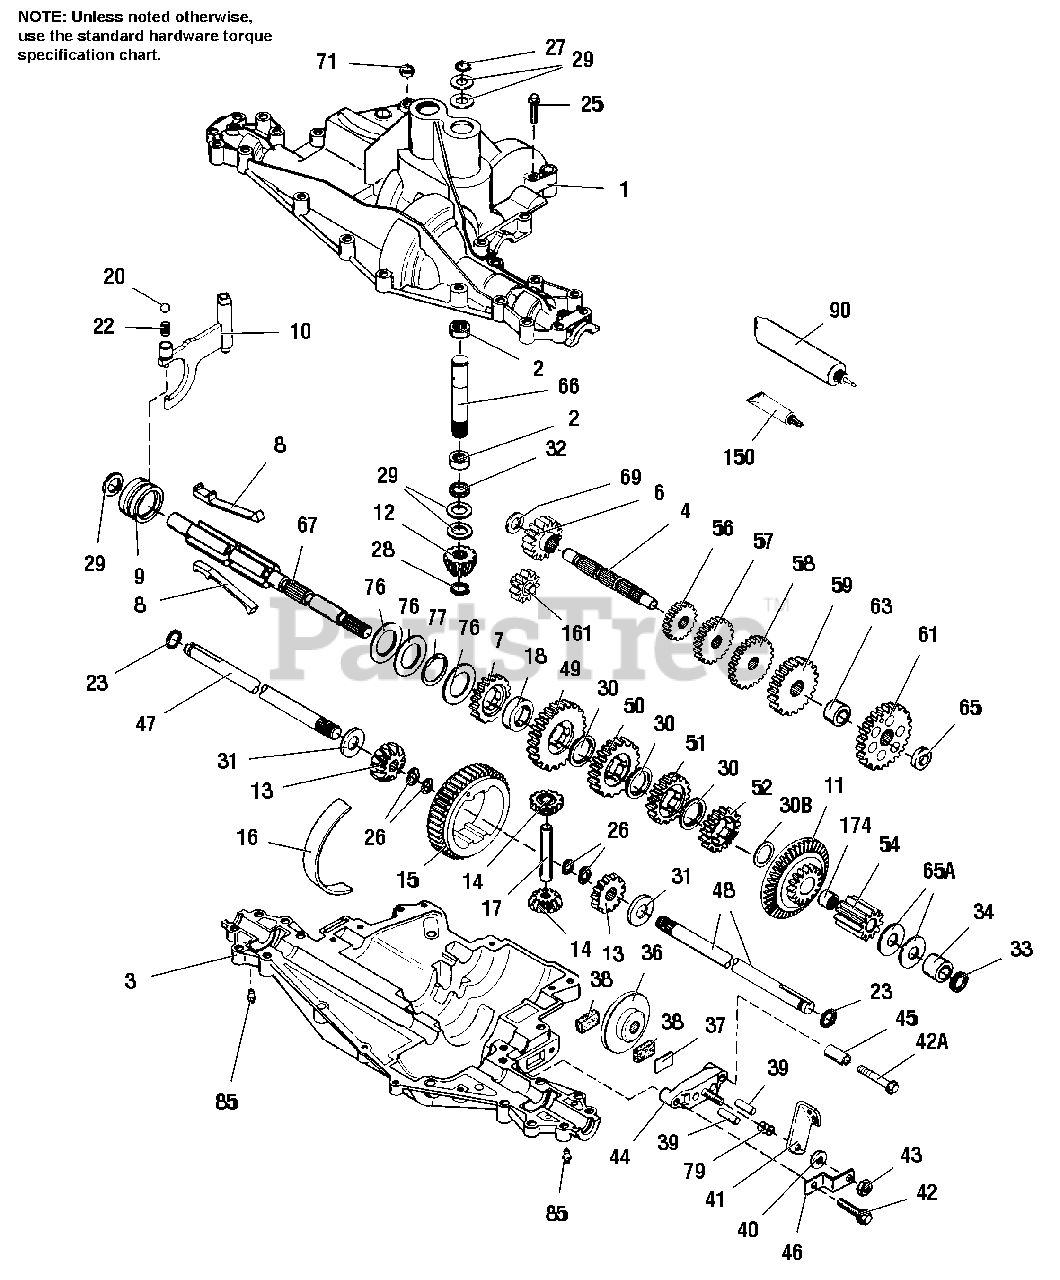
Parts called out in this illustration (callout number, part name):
1	COVER, Transaxle
2	BEARING, Needle
3	CASE, Transaxle
4	COUNTERSHAFT, (4-7/8" Long)
6	GEAR, Spur (16 Teeth)
7	GEAR, Spur (22 Teeth)
8	SHIFT KEY
9	COLLAR, Shifter
10	ROD & FORK ASSY., Shift
11	GEAR, Bevel (44 & 16 Teeth)
12	BEVEL PINION, Input
13	GEAR, Bevel, 13 Teeth
14	PINION, Bevel
15	RING GEAR (43 Teeth)
16	STRIP, Bearing
17	PIN, Drive
18	SPACER, Neutral
20	BALL, Steel
23	SEAL RING
25	SCREW, Hex Hd., Flange, Threadforming, 1/4-20 x 1-1/4
26	RING, Retaining
27	RING, Retaining
28	RING, Retaining
29	WASHER, Thrust
30	WASHER, Thrust
30B	WASHER, Thrust
33	SEAL, Square Cut
36	DISK, Brake
37	PLATE, Brake Pad
38	PAD, Brake
39	PIN, Dowel
40	WASHER, Flat
41	LEVER, Brake
42	SCREW, Hex Hd., Flange, Threadforming,1/4-20 x 1-1/4
42A	SCREW, Hex Hd., Flange, Threadforming, 1/4-20 x 2-1/4
43	NUT, Lock, 5/16-24
44	HOLDER, Brake Pad
46	BRACKET, Brake Lever
47	AXLE, (16-13/16" Long)
48	AXLE, (11-5/8" Long)
49	GEAR, Spur (35 Teeth)
50	GEAR, Spur (27 Teeth)
51	GEAR, Spur (22 Teeth)
52	GEAR, Spur (19 Teeth)
54	GEAR, Spur (11 Teeth)
56	GEAR, Spur (15 Teeth)
57	GEAR, Spur (23 Teeth)
58	GEAR, Spur (28 Teeth)
59	GEAR, Spur (30 Teeth)
61	GEAR, Spur (34 Teeth)
65	WASHER, Thrust
65A	WASHER, Thrust
66	SHAFT, Input (3-5/16" Long)
67	SHAFT, Brake (4 Keyed)
69	WASHER, Thrust
71	SEAL, Square Cut
77	RING, Retaining, Inverted
79	SPRING, Brake
85	FITTING, Lubrication
90	GREASE, 32 Oz. Bottle
150	GASKET ELIMINATOR
161	IDLER ASSY., Reverse
174	BEARING, Needle
